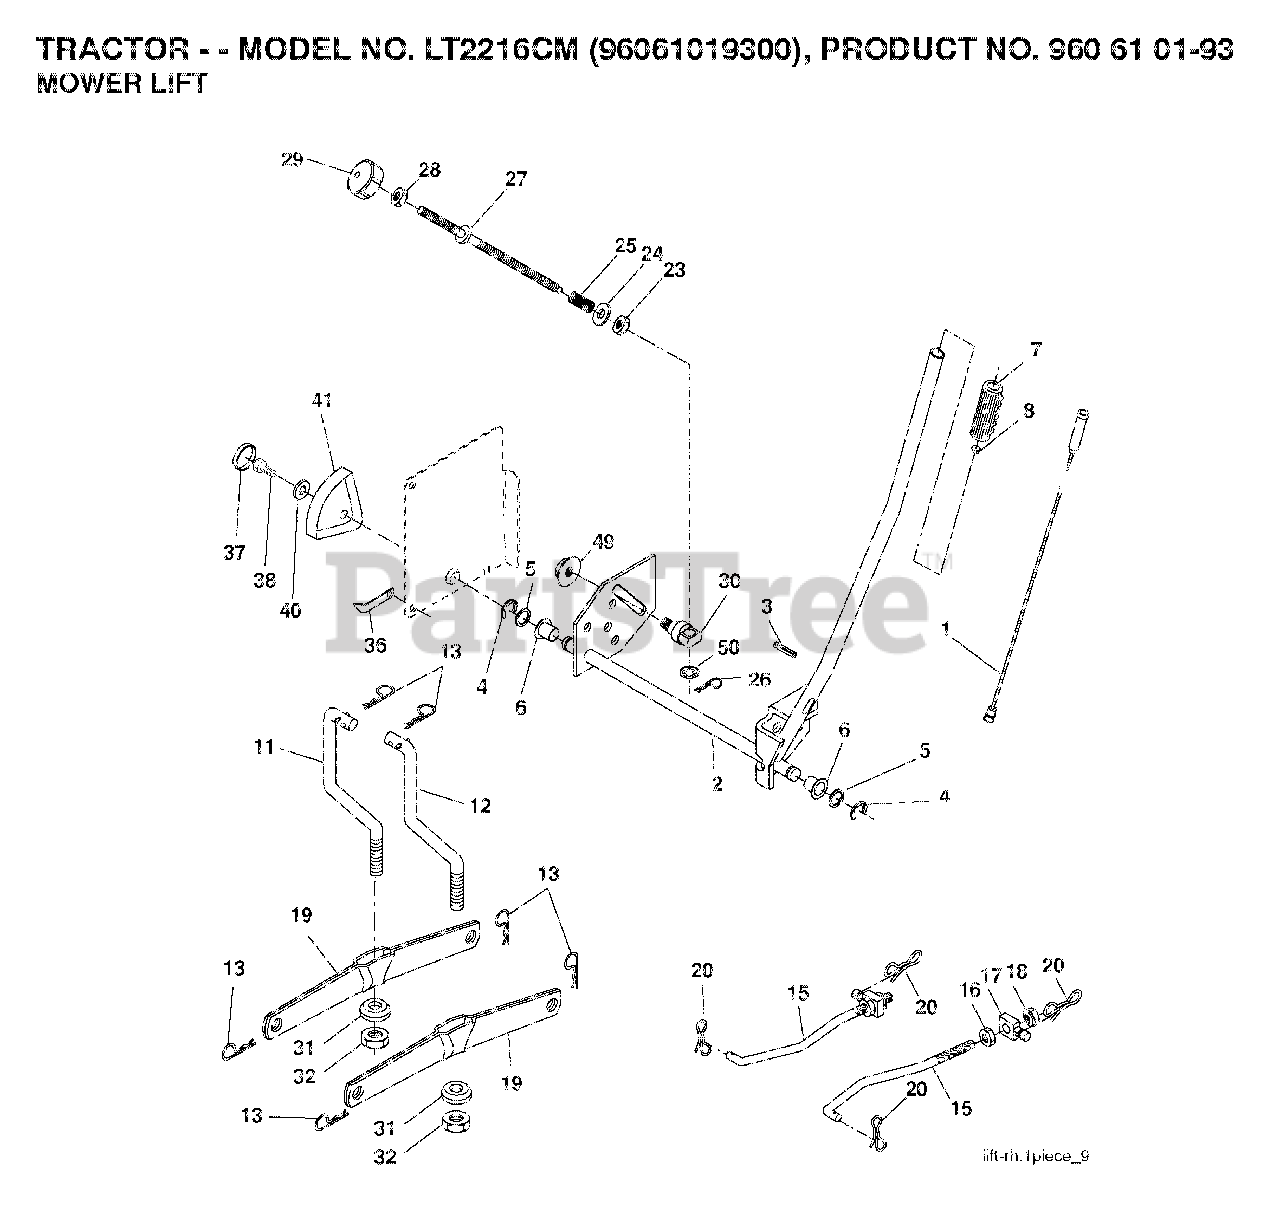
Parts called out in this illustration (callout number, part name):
4	RETAINING RING LT
6	BEARING.NYLON
7	GRIP HANDLE
8	PLUNGER BUT KIT
11	LINK
12	LINK
13	RETAINER-SPRNG RB
15	LINK.SUSPENSION.FRONT
16	NUT
18	NUT
19	ARM.REAR.SUSPENSION
20	PIN.COTTER.7/16.BOW TI
25	SPRING**
26	RETAINER CLIP
27	ROD ADJ LIFT
28	NUT
29	KNOB INF 3/8-16
31	BEARING.PIVOT.LIFT
32	NUT CROWNLOCK 3/8-24
36	POINTER, HEIGHT INDICATOR
37	PLUG,HOLE
38	SCREW 5/16-18X1
41	HEIGHT INDICATOR
49	NUT
50	NUT PUSH M
